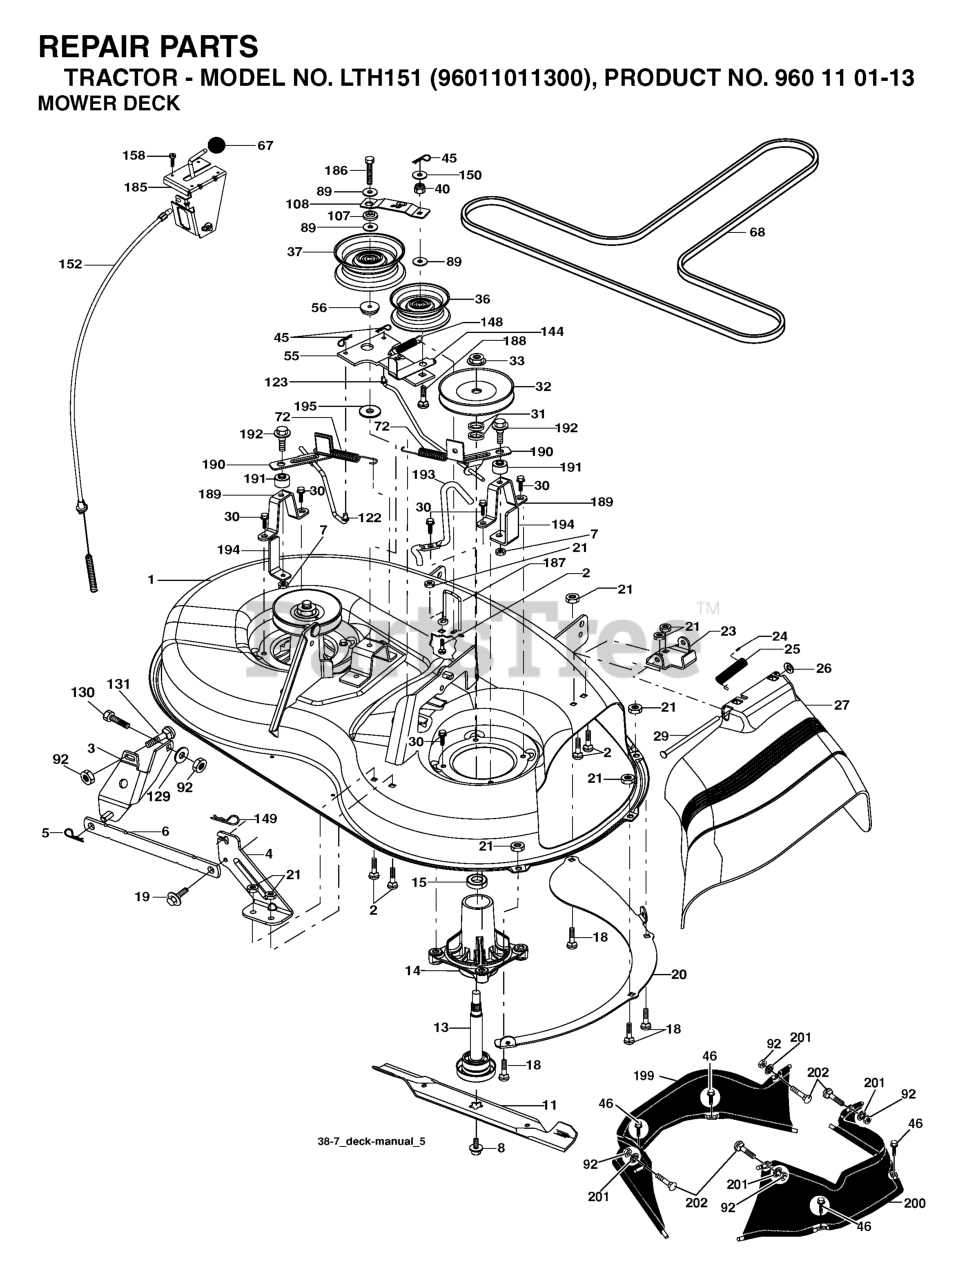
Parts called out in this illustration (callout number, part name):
1	DECK SVCX1 38/94 192556X431
2	RP BOLT 5/16-18 X3/4 ZN/YEL GR
3	BRKT ASM SWAY BAR
4	BRACKET DECK SWAY BAR 38"/42"
5	RETAINER-SPRNG RB
6	BAR SWAY DECK
7	NUT.71038.31-18.HEX.NYLOCK
8	BOLT.WASHER.ASM.7/16-2
11	BLADE 38" PREMIUM
13	SHAFT.ASM.MDRL.N/GREASE.38
14	RP.HOUSING.MANDREL.4PT.
18	BOLT
19	BOLT SHD 5/16-18
20	BAFFLE.VORTEX.FRONT.38"
21	LOCKNUT
23	BRKT.DEFLECTOR.38"2005+
24	CAP-SLEEVE LT
25	SPRING.TORSION.DEFLECT
26	NUT PUSH M
27	SHIELD ASM.DFLCTR MWR.38-7"BLK
29	ROD.HINGE
30	SCREW, WASHER HEAD
31	WASHER.SPACER.MANDREL
32	PULLEY MANDREL
33	NUT, FLG TOPLOCK 9/16"
36	FLAT IDLER PULLEY
37	PULLEY.IDLER.FLAT.UNPLATED
45	RETAINER M
46	SCREW.1/4-20X5/8
56	SPACER.RETAINER.MOWER
67	KNOB T (3/8 HOLE)
68	V-BELT.MOWER.38"2005+
72	SPRING.BRAKE.RETURN.38"
89	WASHER
92	NUT
107	SPACER.IDLER.ARM
108	STIFFENER.IDLER.ARM
122	LINKAGE.BRAKE.LH.38"
123	LINKAGE.BRAKE.RH.38"
129	WASHER
131	BOLT D
144	KEEPER BELT
148	IDLER RETURN SPRING
149	SPRING.RETAINER.YELLOW.ZINC
152	CABLE.CLUTCH.38".SERVICE
158	SCREW
185	HEAD ASM. CABLE CLUTCH
186	SCREW.HXWSH.3/8
187	KEEPER BELT
188	BOLT, CARRIAGE IDLER
189	STAND, BRAKE
190	ARM, BRAKE
191	BRAKE.SPACER.38".DECK
192	BOLT/WASHER ASM 5/16-18
193	KEEPER BELT RH MANDREL
194	GUARD BRAKE
201	PUSH.NUT.ROUND.3/8.DIAM
202	BOLT D
204	NUT, CROWNLOCK
